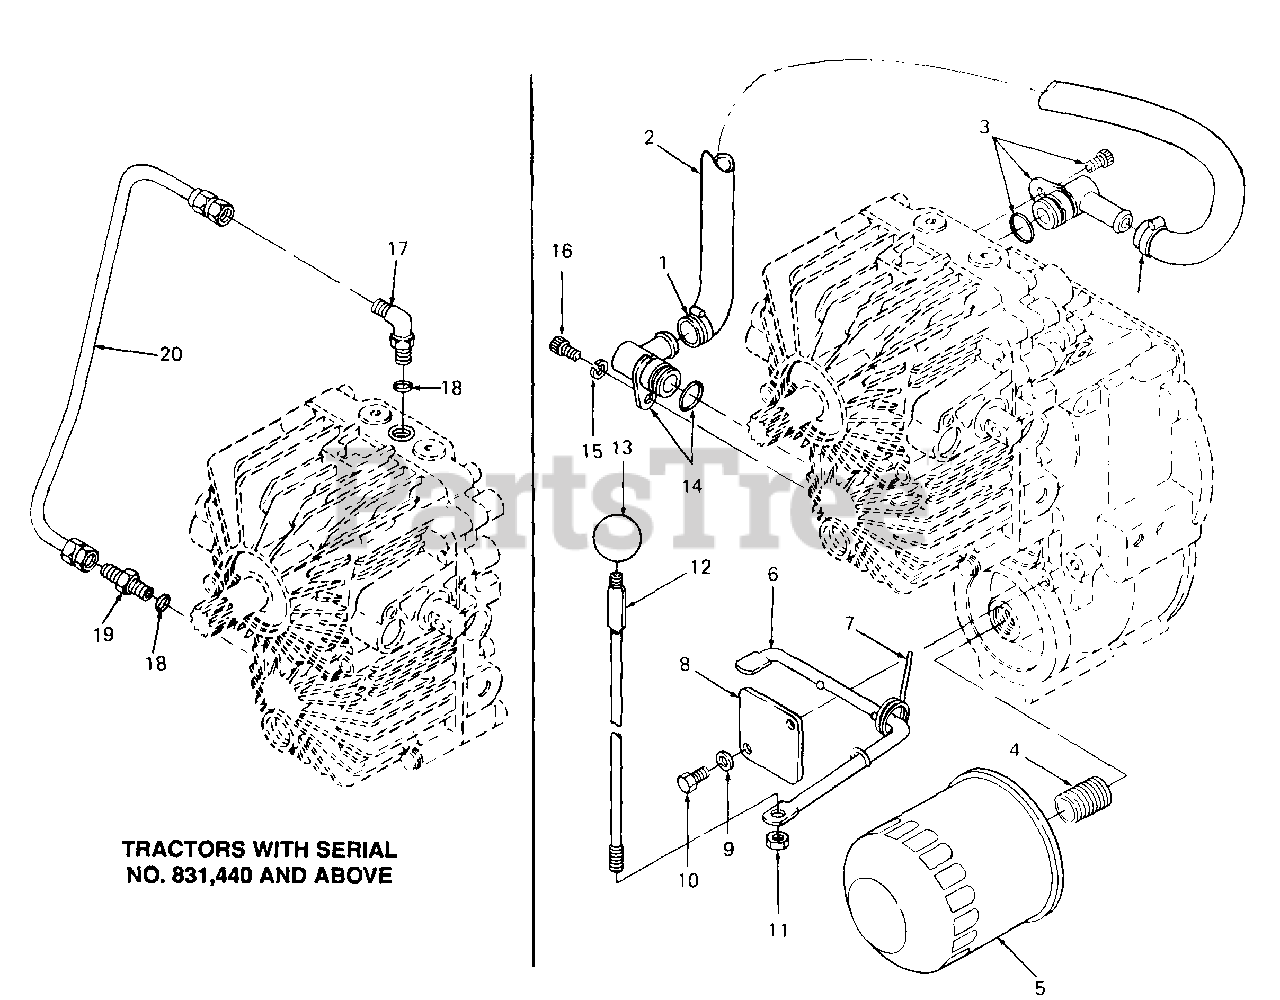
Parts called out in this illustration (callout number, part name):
1	Clamp, Hose, 5/8
2	Line, Pickup
3	Fitting Assembly
4	Nipple, Oil Filter
5	Filter, Oil
6	Rod, Dump Valve Lower
7	Spring, Torsion
8	Plate, Retaining
9	Washer, Lock, 1/4
10	Screw, Hex Cap, 1/4-20 X .50 Lg GR5
11	Nut, Hex Top Lock, 1/4-20
12	Rod, Dump Valve Upper
13	Knob, Ball
14	Fitting Assembly
15	Washer, Lock, 1/4
16	Screw, Socket Head, 1/4-20 X .65 Lg
17	Elbow, 90 Degree Tube
18	O-Ring, 3/8 OD Tube
19	Connector, 37 Degree Tube
20	Line, Metal Pickup
